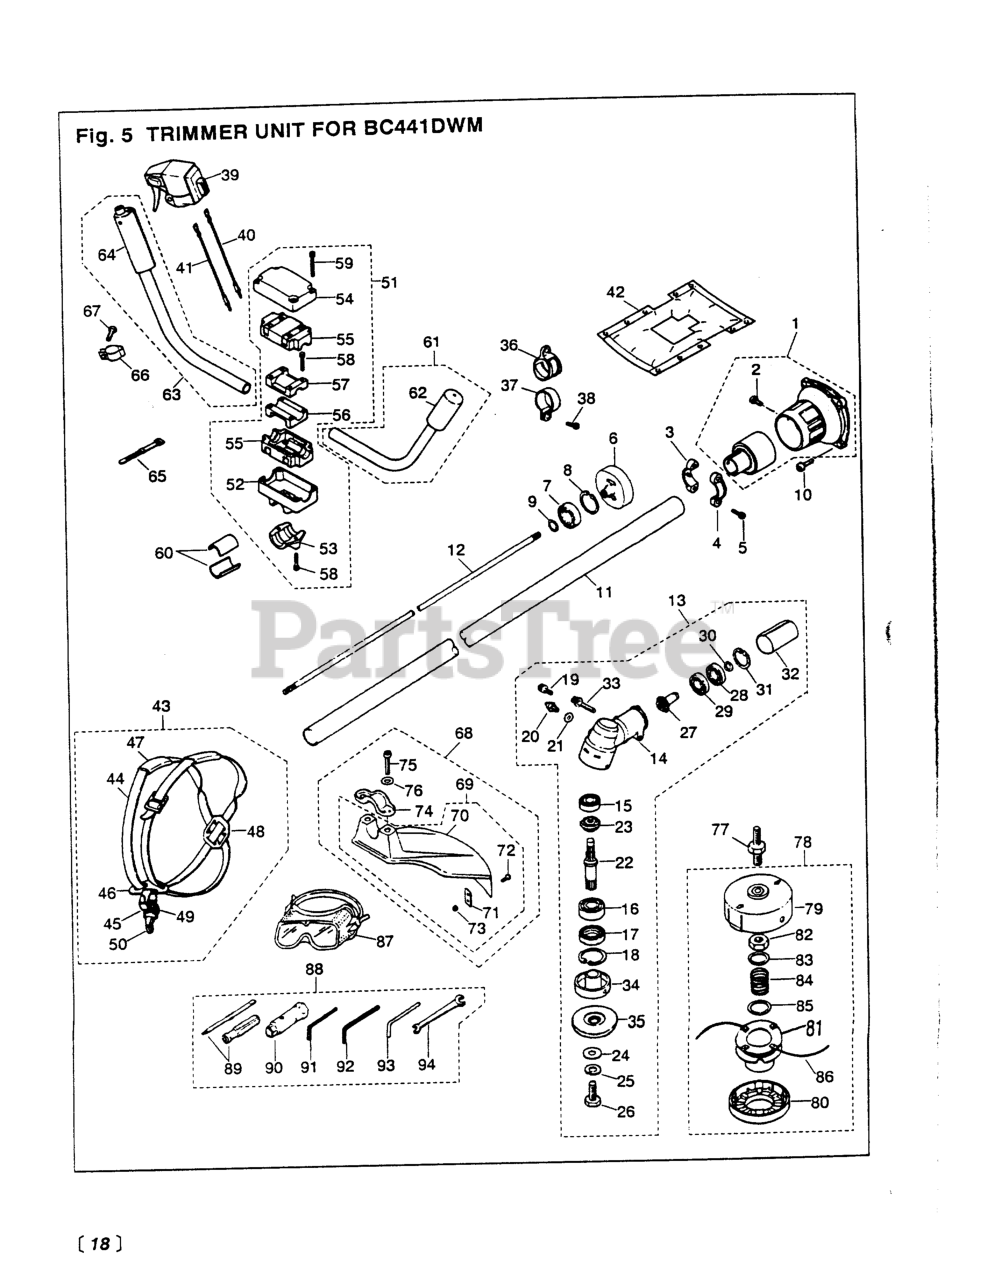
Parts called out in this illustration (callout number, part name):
2	SCREW, M6 x 10
5	BOLT
6	DRUM, SPLINED
7	BEARING
8	RING, SNAP, M35 X 1.5
9	RING, SNAP, M15 X 1.0
11	PIPE (USE -12101)
12	SHAFT (USE -12212)
15	BEARING (RPLS T3403-13510)
18	RING, SNAP, M35 X 1.5
19	BOLT, M5 X 10
20	FITTING, GREASE
21	WASHER, M6 X .8
22	SHAFT (RPLS -13211)
24	WASHER, M10 x 3.2
25	WASHER
26	BOLT (REPLACES 3130-13260)
28	BEARING
29	BEARING
31	RING, SNAP, M28 x 1.2
33	BOLT, M6 x 1.35
34	HOLDER (A) (RPLS -13240)
35	HOLDER (B)
36	HANGER
37	CLAMP
38	SCREW, M5 x 25
39	LEVER ASSEMBLY
40	CORD A (RED)
41	CORD (RPLS -14720)
47	PROTECTOR
53	CAP, LOWER
54	CAP, UPPER
55	ABSORBER
56	CLAMP (A)
57	CLAMP (B)
58	BOLT, M5 X 25
59	BOLT, M5 X 30
61	HANDLE COMPL, LEFT
63	HANDLE COMPL, RIGHT
64	GRIP
65	BAND
66	CLAMP
67	SCREW, M5 X 16
71	BLADE
72	SCREW, M5 x 12
73	NUT
74	CLAMP
75	BOLT, M6 x 1.30
76	WASHER, M6 X 15
77	ARBOR, 10MM
78	6
80	COVER
82	NUT (NO LONGER AVAILABLE)
83	PLATE, LARGE
85	PLATE, SMALL
89	SCREWDRIVER
91	WRENCH (TOOL)
92	WRENCH (TOOL)
93	BAR
94	SPANNER, 8 X 10 (RPLS 2540- )
